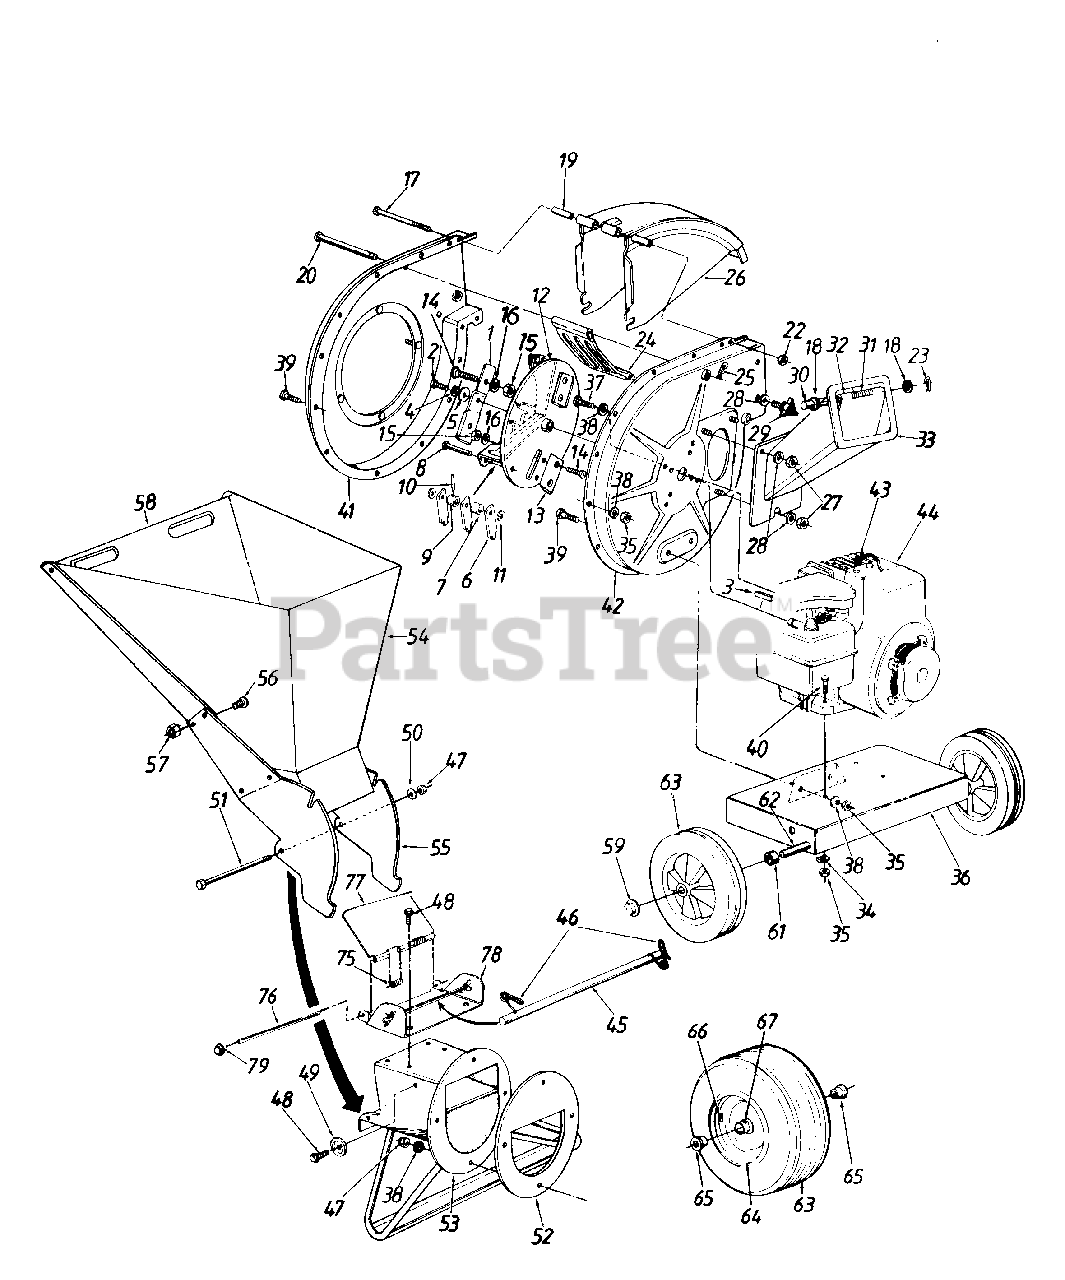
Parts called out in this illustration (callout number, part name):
1	Blade
2	Hex Bolt 3/8-24 x 2.0" Lg. (Gr. 8)
3	Sq. Key 1/4 x 2.0" Lg.
4	L-Wash. 3/8" I.D. H.D.
5	Fl-Wash. .406" I.D. x 1.25" O.D. Hdn.
6	Flail
7	Flail Spacer
8	Clevis Pin .496" Dia.
9	Flail Spacer w/.160" Dia. Hole
10	Spring Roll Pin 1.12" Lg.
11	Fl-Wash. .531" I.D. x .94" O.D.
12	Impeller Ass'y.
13	Chipper Blade
14	Flat Hd. Scr. 5/16-24 x .75" Lg.
15	Hex Top L-Nut 5/16-24 (Gr. 5)
16	L-Wash. 5/16" I.D.
17	Hex Bolt 1/4-20 x 3.75" Lg.
18	Fl-Wash. .281" I.D. x .5" O.D.
19	Chute Hinge Spacer 1.66" Lg.
20	Clevis Pin .5" Dia. x 4.62" Lg.
22	Hex Ctr. L-Nut 1/4-20 Thd.
23	Cotter Pin
24	Shredder Screen
25	Internal Cotter Pin 3/8" Dia.
27	Hex Nut 5/16-18 Thd. (Gr. 5)
28	Bell-Wash. .345" I.D. x .88"
29	Hand Knob
30	Chipper Door Rod
31	Torsion Spring 1.14" Lg.
35	Hex Nut 5/16-18 Thd. (Gr. 5)
37	Hex Bolt 5/16-24 x .75" Lg.
38	L-Wash. 5/16" I.D.
39	Hex Bolt 5/16-18 x .75" Lg. (Gr. 5)
40	Hex Bolt 5/16-18 x 1.75" Lg.
44	Engine
45	Release Bar
46	Torsion Spring 1.06" Lg.
47	Elastic Lock Nut 5/16-18 Thd.
48	Hex Wash. Hd. Self-Tap Scr. 5/16-18 x .75" Lg.
49	Stop Washer
50	Fl-Wash. 5/16" I.D.
51	Hex Bolt 5/16-18 x 8.38" Lg.
57	Hex L-Nut 1/4-20 Thd.
61	Spacer .64" I.D. x .38" Lg.
62	Shredder Axle (645, 242A645)
62	Shredder Axle (648, 242A648)
63	Wheel Ass'y. Comp. (645, 2424645)
63	Wheel Ass'y. Comp. (648, 242A648)
63	Tire Only (648, 242A648)
64	Rim Only (648, 242A648)
65	Flange Bearing .632" I.D. (648, 242A648)
66	Air Valve (648, 2424648)
67	Grease Fitting (648, 242A648)
75	Torsion Spring
76	Hopper Door Rod
